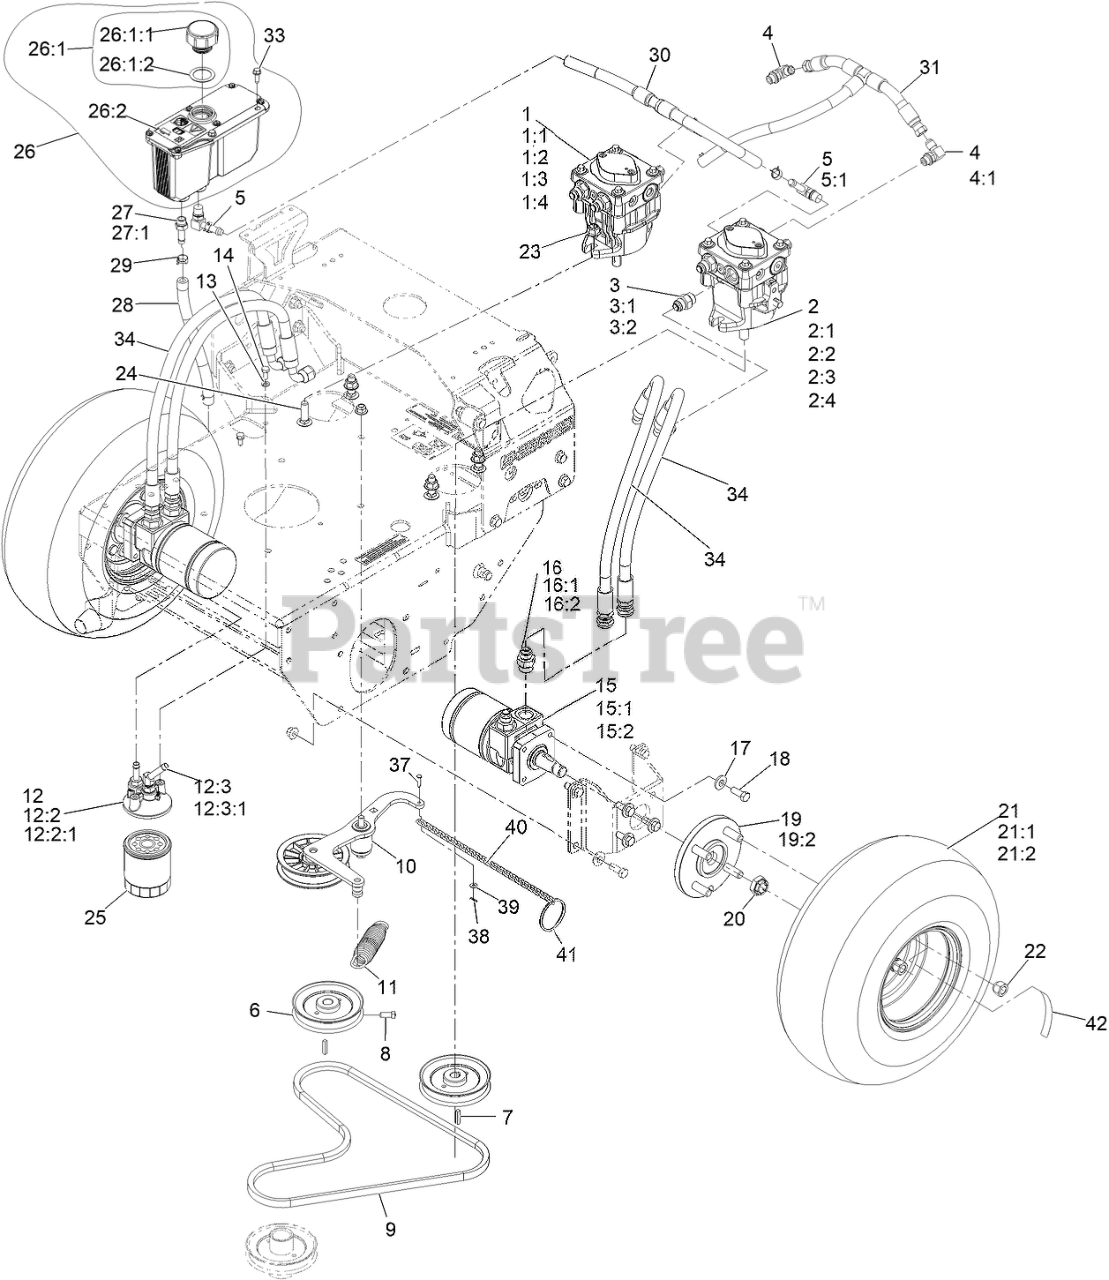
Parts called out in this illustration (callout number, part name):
1	RH HYD PUMP ASM
1:1	INPUT SHAFT KIT
1:2	BEARING-THRUST
1:3	CYLINDER BLOCK KIT
1:4	SEAL OVERHAUL KIT
2	LH HYD PUMP ASM
2:1	INPUT SHAFT KIT
2:2	BEARING-THRUST
2:3	CYLINDER BLOCK KIT
2:4	SEAL OVERHAUL KIT
3	FITTING-STRAIGHT
4	FITTING-ELBOW, 90 DEG
4:1	O-RING
5	FITTING-ELBOW, 90
5:1	O-RING
6	SHEAVE ASM
8	SCREW-SET, SQH
9	BELT
10	ASM, PUMP IDLER
11	SPRING-EXTENSION
12	ASM, FILTER HEAD
12:2	ADAPTER-STRAIGHT
12:2:1	O-RING
12:3	FITTING-BARBED, 45 DEG
12:3:1	O-RING
13	WASHER-LOCK
14	SCREW-HH
15	HYD MOTOR ASM
15:1	SEAL KIT
15:2	BEARING AND SEAL KIT
16	FITTING-STRAIGHT
16:1	O-RING
17	WASHER-BELLEVILLE
18	SCREW-HH
19	WHEEL HUB ASM
19:2	STUD-WHEEL
20	NUT-LOCK
21	WHEEL AND TIRE ASM
21:1	TIRE-TURFMASTER
21:2	RIM-WHEEL
22	NUT-LUG
23	NUT-HF, NI
24	BOLT-CARR
25	FILTER-25 MICRON, BI-DIRECTIONAL
26:1	Reservoir-HYD
26:1:1	Cap-Reservoir, HYD
26:1:2	GASKET-CAP
26:2	DECAL-WARNING
27	ADAPTER-STRAIGHT
27:1	O-RING
28	HOSE-CHARGE
29	CLAMP-HOSE
30	HOSE-CASE DRAIN
31	HOSE-CHARGE
33	SCREW-HWH, THREAD ROLL
34	HYD HOSE ASM
37	PIN-CLEVIS
38	PIN-HAIR
39	WASHER-PLAIN
40	CHAIN-LINK, TWIST
41	RING-SPLIT
42	DECAL-TORQUE WHEEL LUG-HU
